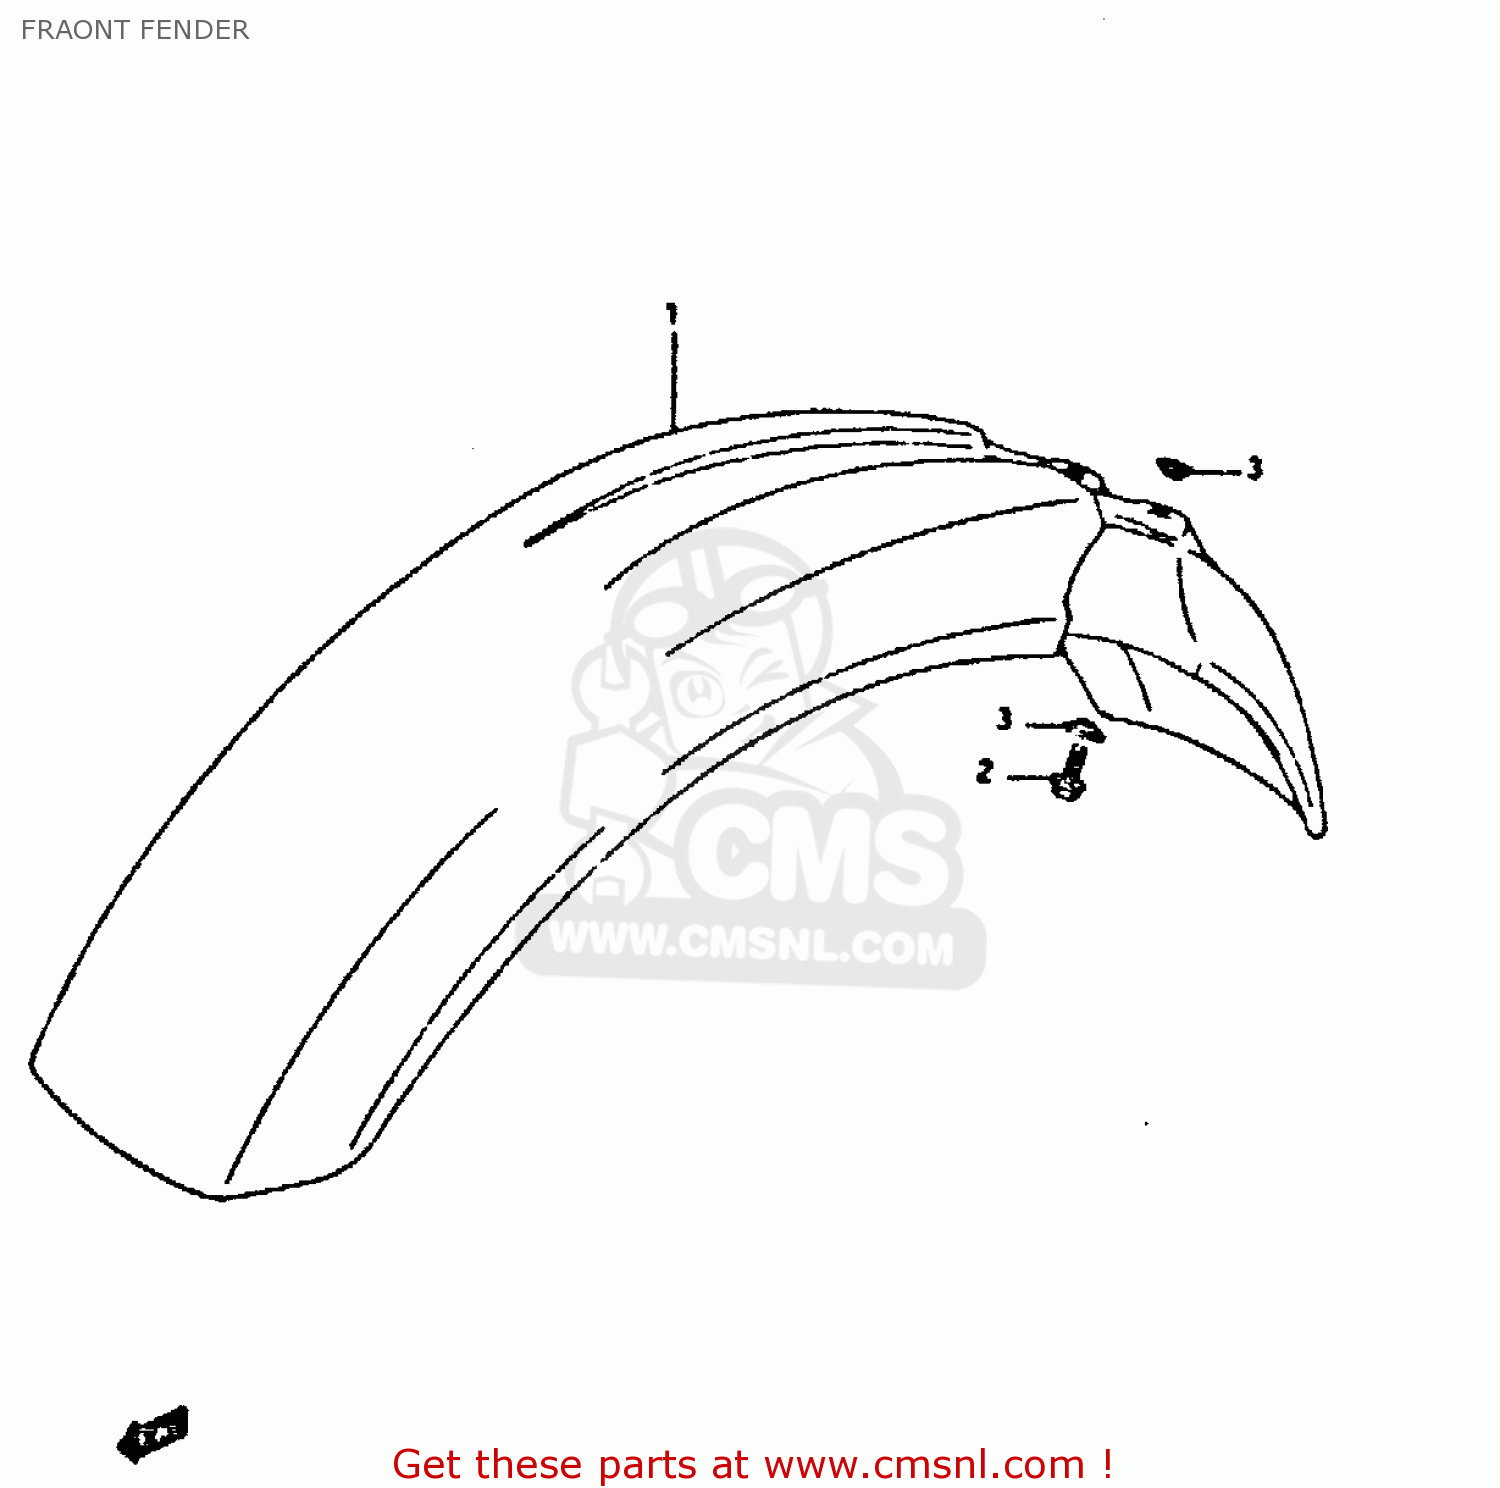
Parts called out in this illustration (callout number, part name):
1	FENDER,FR
2	BOLT
3	WASHER
